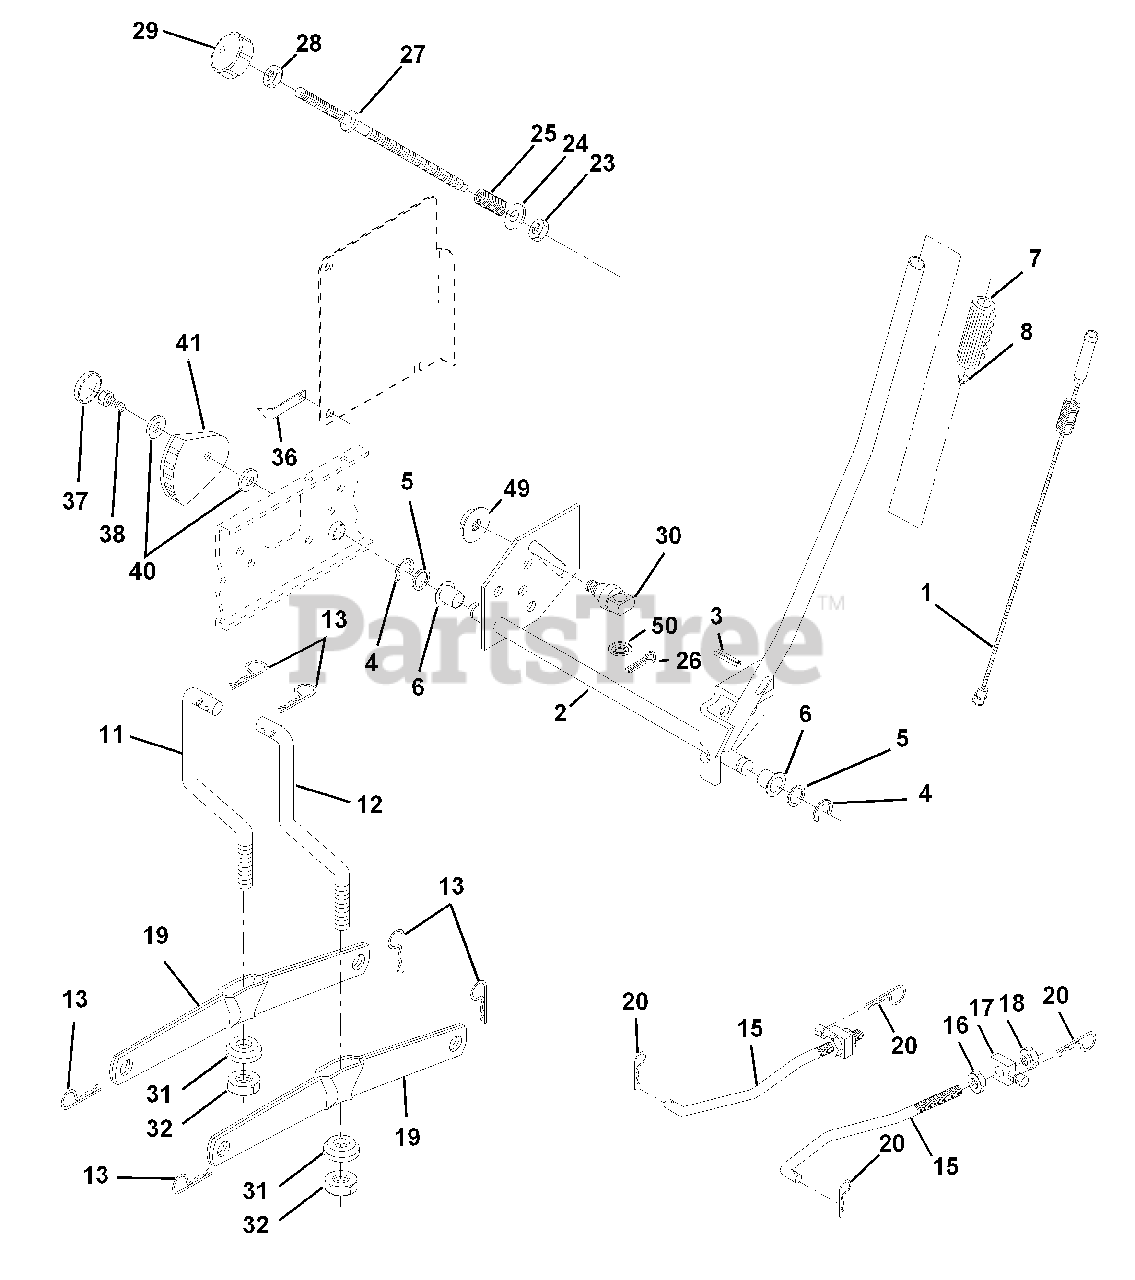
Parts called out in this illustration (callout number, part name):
1	Wire Asm Inner/Spring W/Plunger LT
2	Shaft Asm Lift RH w/Inf
3	Pin Groove 1 500 Zinc
4	E Ring #5133-62
5	Washer 21/32 X 1 X 21 Ga
6	Bearing Nylon Blk 629 Id
7	Grip Handle Fluted Blk
8	Button Plunger Black
11	Link Lift LH Fixed Length
12	Link Lift RH Fixed Length
13	Retainer Spring
15	Link Front
16	Nut Jam Hex 1/2-13 Unc
17	Trunnion Blk Zinc
18	Nut Lock W/wsh 1/2-13unc
19	Arm Suspension Rear
20	Retainer Spring
23	Nut Special
24	Washer 13/32 X 5/8 X 16 Ga
25	Spring 2-1/8"
26	Pin Cotter 3/32 X 1/2
27	Rod Adj Lift Zinc 7.49 Wrk Lg
28	Nut Hex Jam 3/8-16 Unc
29	Knob Inf 3/8-16 Unc Blk W/sym
30	Trunnion Infin Height
31	Bearing Pvt Lift Spherical
32	Nut Crownlock 3/8 - 24
36	Indicator Height STLT
37	Plug Hole Blk 1.485/1.515 Dia.
38	Screw Thdrol 5/16-18 x 3/4
40	Washer 11/32 x 1-1/2 10 Ga.
41	Scale Ind. Height Blk.
49	Nut Hex Flange Lock
50	Nut, Push Phos & Oil
